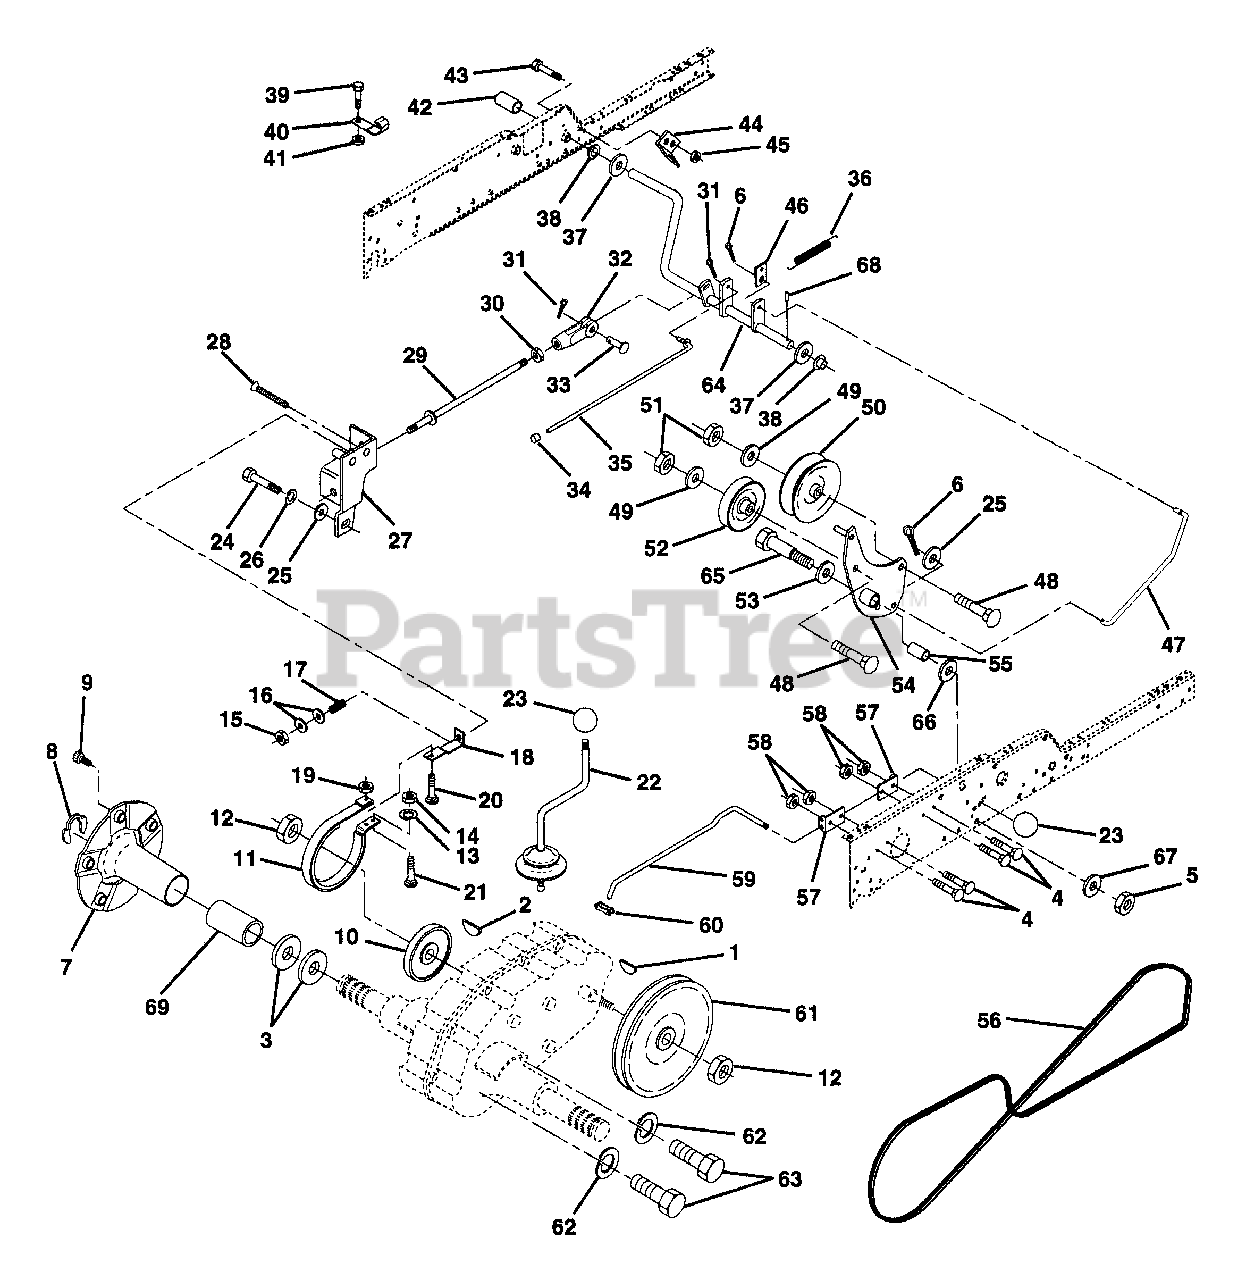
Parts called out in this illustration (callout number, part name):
1	Key, Woodruff
2	Key, Woodruff
3	Washer, Thrust, Axle
4	Bolt 5/16-18 x 3/4
5	Nut, Crownlock 3/8-16
6	Pin, Cotter 1/8 x 3/4
7	Wheel Hub Assembly
10	Drum, Brake
11	Band, Brake
12	Locknut 1/2-20
13	Washer, Lock 1/4
14	Nut, Hex 1/4-20
15	Locknut 3/8-24
16	Washer 13/32 x 1 x 14 Gauge
17	Spring, Compression
18	Guide, Brake Rod
19	Locknut 5/16-18
20	Bolt, Carriage 5/18-18 x 3/4
21	Bolt, Carriage 1/4-20 x 5/8
22	Gearshift Lever Assembly
24	Bolt, Hex Head 3/8-16 x 7/8
25	Washer 13/32 x 13/16 x 16 Gauge
26	Washer, Lock 3/8
27	Bracket, Brake
28	Screw, Machine, Flat Head 3/8-16 x 3/4
30	Nut, Hex 3/8-24
31	Pin, Cotter 3/32 x 3/4
33	Pin, Clevis
34	Cap, Plunger
35	Rod, Parking Brake
36	Spring, Extension, Clutch
37	Washer 25/32 x 1-1/4 x 16 Gauge
39	Screw, Fin. #10-24 x 1
40	Actuator, Interlock Switch
41	Locknut #10-24
42	Cover, Clutch/Brake Pedal
43	Bolt, Hex 1/4-20 x 3/4
44	Bracket, Interlock
45	Nut, Lock w/Inst 1/4-20
46	Retainer, Spring
47	Clutch Rod
48	Bolt, Carriage 3/8-16 x 1-3/4
49	Washer 13/32 x 7/8 x 13 Gauge
50	Idler, Flat
51	Locknut, Hex 3/8-16
52	Idler, Grooved
53	Washer, Hardened
54	Clutch Arm Assembly
55	Bearing, Idler
57	Bracket, Shift Rod, Hi-Lo
58	Locknut, Hex, with Washer Insert 5/16-18
59	Shift Rod, Hi-Lo
60	Spring Clip, Connecting Link
61	Pulley, Transaxle
62	Washer, Lock 7/16
63	Bolt, Hex Head 7/16-14 x 1-1/4
64	Shaft, Clutch/Brake Pedal
65	Bolt, Shoulder
66	Washer, Hardened
67	Washer Flat
69	Hub, Cover
